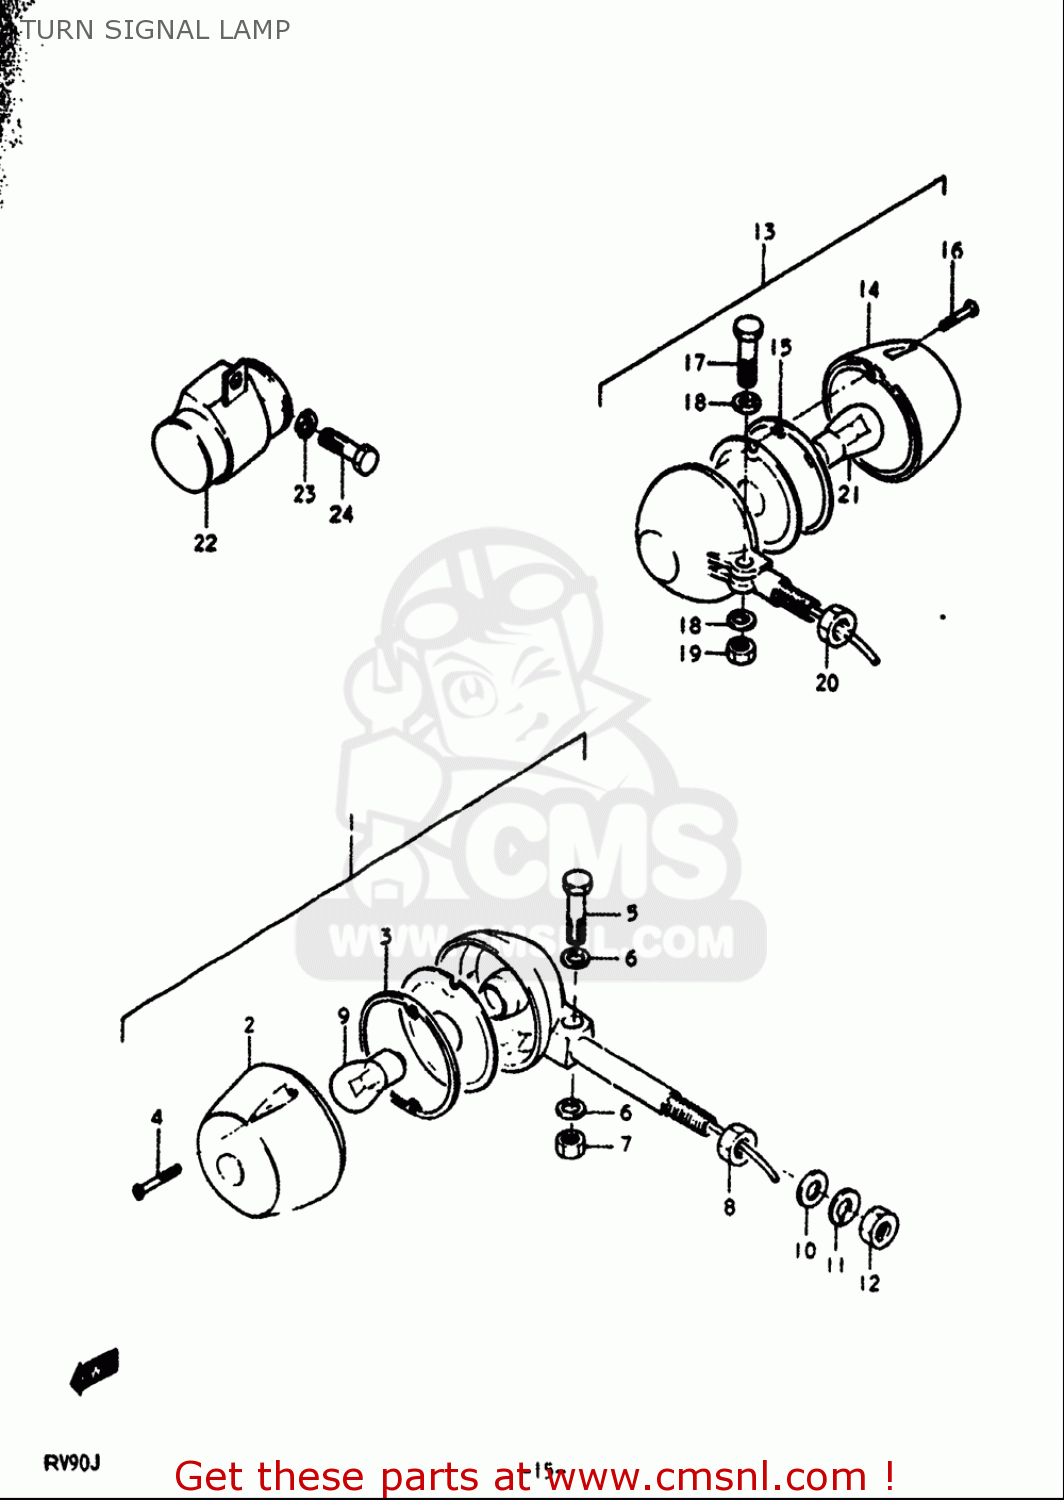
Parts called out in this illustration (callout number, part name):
2	LENS,TURNSIGNAL
3	GASKET,TURNSIGNAL LENS (NAS)
4	SCREW
6	WASHER
7	NUT
8	NUT
9	BULB(6V17W,STANLEY,A4513A)
10	WASHER
11	WASHER,LOCK
12	NUT
14	LENS,RR TURNSIGNAL LAMP
15	GASKET,TURNSIGNAL LENS (NAS)
16	SCREW
18	WASHER
19	NUT
20	NUT
21	BULB(6V17W,STANLEY,A4513A)
22	RELAY ASSY,TURNSIGNAL
23	WASHER,LOCK
24	BOLT
